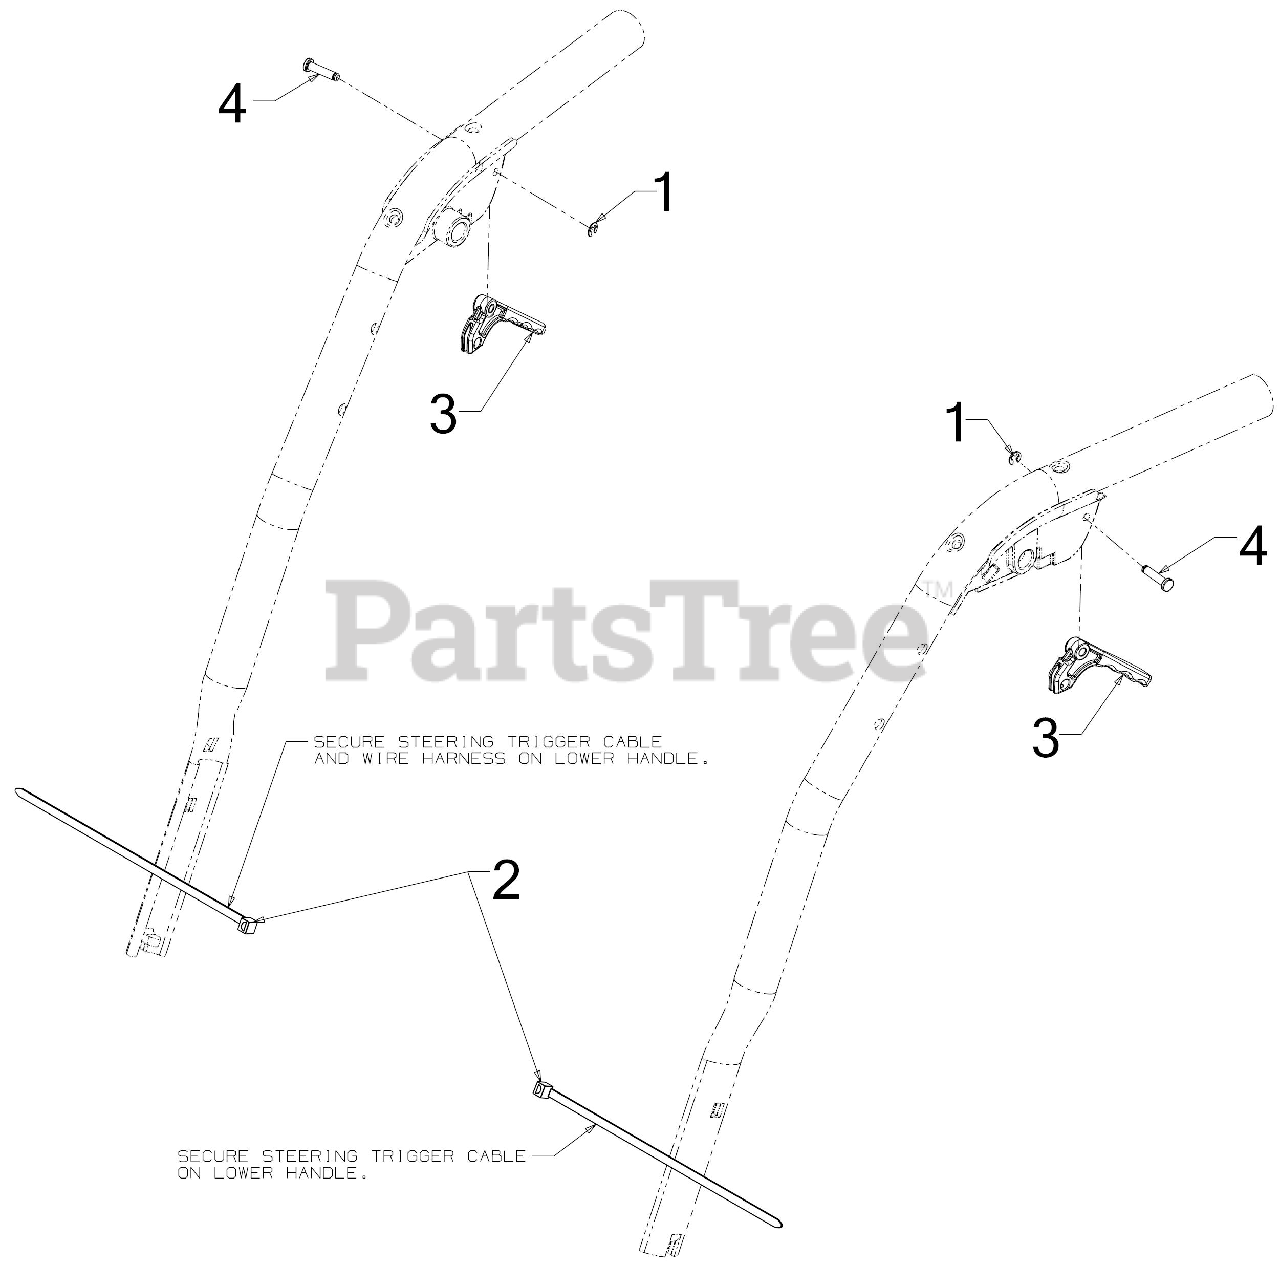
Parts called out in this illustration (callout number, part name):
2	7" CABLE TIE
3	TRIGGER CLUTCH LOCK
4	STEERING TRIGGER PIN 3/16
